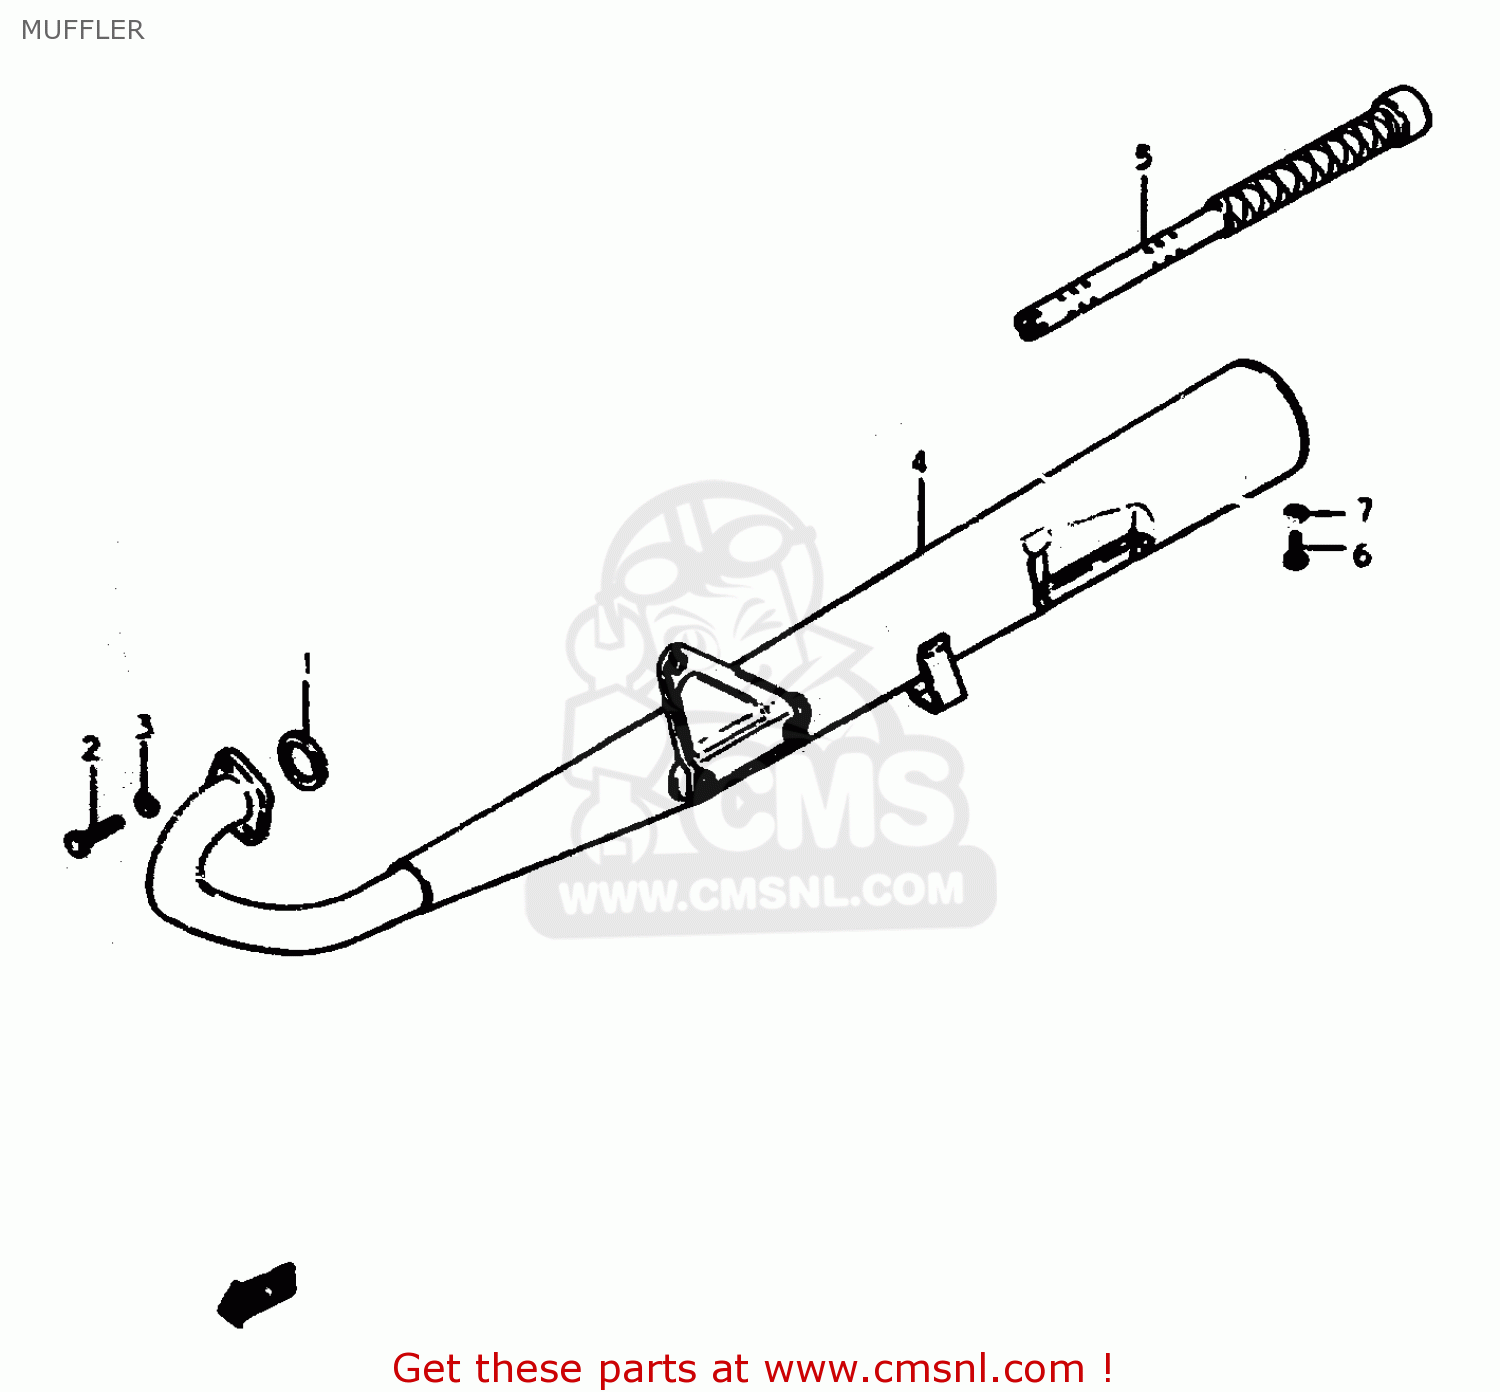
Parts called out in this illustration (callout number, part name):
1	GASKET,EXHAUST PIPE (NAS)
2	BOLT
3	LOCK WASHER
4	MUFFLER ASSY
5	PIPE, BAFFLE
6	SCREW
7	LOCK WASHER
